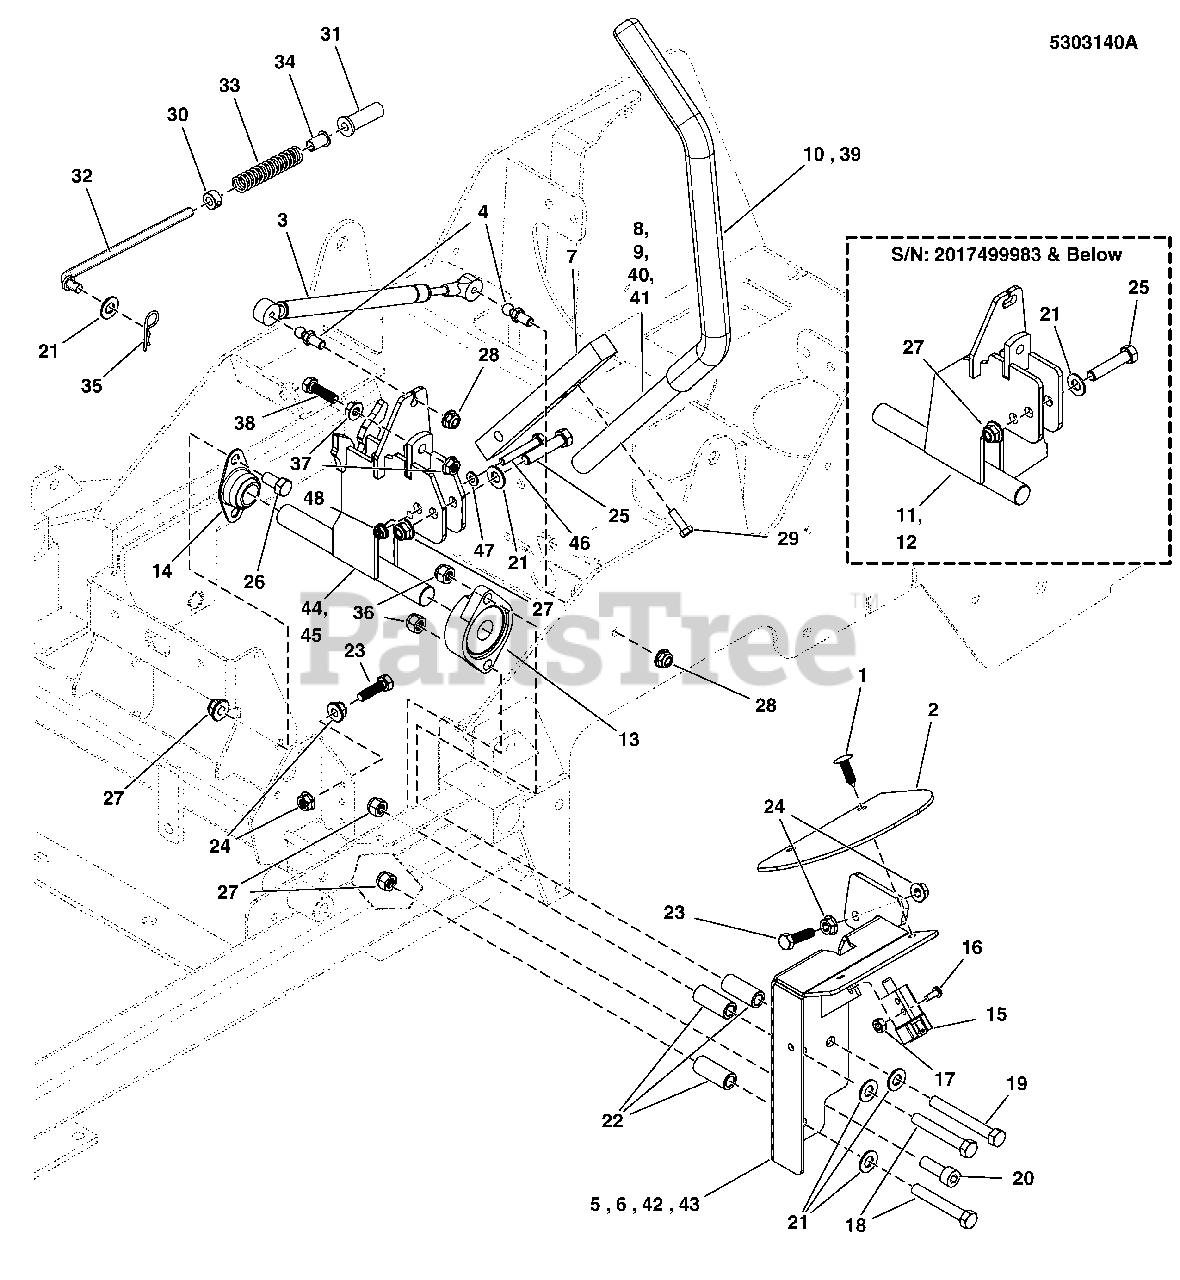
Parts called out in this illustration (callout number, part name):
1	PUSH RIVET (TREE TYPE), BLACK
2	GUARD, RUBBER MOT CTRS - IS500Z
3	DAMPENER, CONTROL,#(P6709/P3610)
4	BALL STUD, 5/16 X .50,# PC-477-2)
5	WELD, NEUTRAL LOCK - LH - IS500Z - BLK
6	WELD, NEUTRAL LOCK - RH - IS500Z - BLK
7	MOUNT, CONTROL ARM - BLK
8	WELD, HANDLE MOTION CONTROL LH - BLK
9	WELD, HANDLE MOTION CONTROL RH - BLK
10	GRIP, FOAM, 3/4" ID, 16"" LONG
11	WELD, SHAFT MOTION CONTROL, LH - BLK
12	WELD, SHAFT MOTION CONTROL, RH - BLK
13	BEARING, FLANGE
14	BEARING, BRONZE FLANGE, 3/4"
15	Refer to: Electrical Group
16	SCREW, #10-24 X 1/2" ROUND PHILLIPS
17	NUT, HEX, #10-24
18	BOLT, 3/8-16 X 2-1/2" GD5 CZ
19	BOLT, 3/8-16 X 3" GD5 CZ
20	BOLT, Allen Head, 3/8-16 x 1-1/4
21	WASHER, 3/8 SAE
22	SPACER, .39 X .63 X 1.50, CZ
23	BOLT, 5/16-18 X 1-3/4 TFL, GD5 YZ
24	NUT, 5/16-18 HEX SERRATED FLANGE (SMALL)
25	BOLT, 3/8-16 X 1-3/4" GD5 CZ
26	BOLT, 3/8-16 X 3/4" GD5 CZ
27	NUT, 3/8 - 16 HEX NYLOCK FLANGE
28	NUT, 5/16-18 HEX NYLOCK FLANGE NUT
29	SCREW, 5/16-18x0.750, GR5, WHIZ-LOCK, ZC
30	COLLAR, 3/8" Set
31	FLANGED BUSHING, 3/8IDX.63ODX.8125FL
32	ROD, NEUTRAL RETURN, CZ
33	SPRING, REVERSE RETURN
34	BUSHING, FLANGE 3/8ID X 7/8 LONG
35	3/32 X 1-5/8 HAIR PIN CLIP
36	NUT, 3/8-16 HEX NYLON LOCK
37	NUT, 5/16-18 HEX SERRATED FLANGE (LARGE)
38	BOLT, 5/16-18 X 1-1/4" GD5 YZ
39	GRIP, FOAM, 1" ID, 16" LONG
40	WELD, HANDLE MOTION CNTRL, 19.0, 1.0, LH - BLK
41	WELD, HANDLE MOTION CNTRL, 19.0, 1.0, RH - BLK
42	WELD, NEUTRAL LOCK - LH - BLK
43	WELD, NEUTRAL LOCK - RH - BLK
44	WELD, SHAFT MOTION CONTROL, LH - BLK
45	WELD, SHAFT MOTION CONTROL, RH - BLK
46	BOLT, 1/4-20 X 1-1/2 GD5 CZ
47	WASHER, 1/4 SAE
48	NUT, 1/4-20 Hex Nylock Flange
